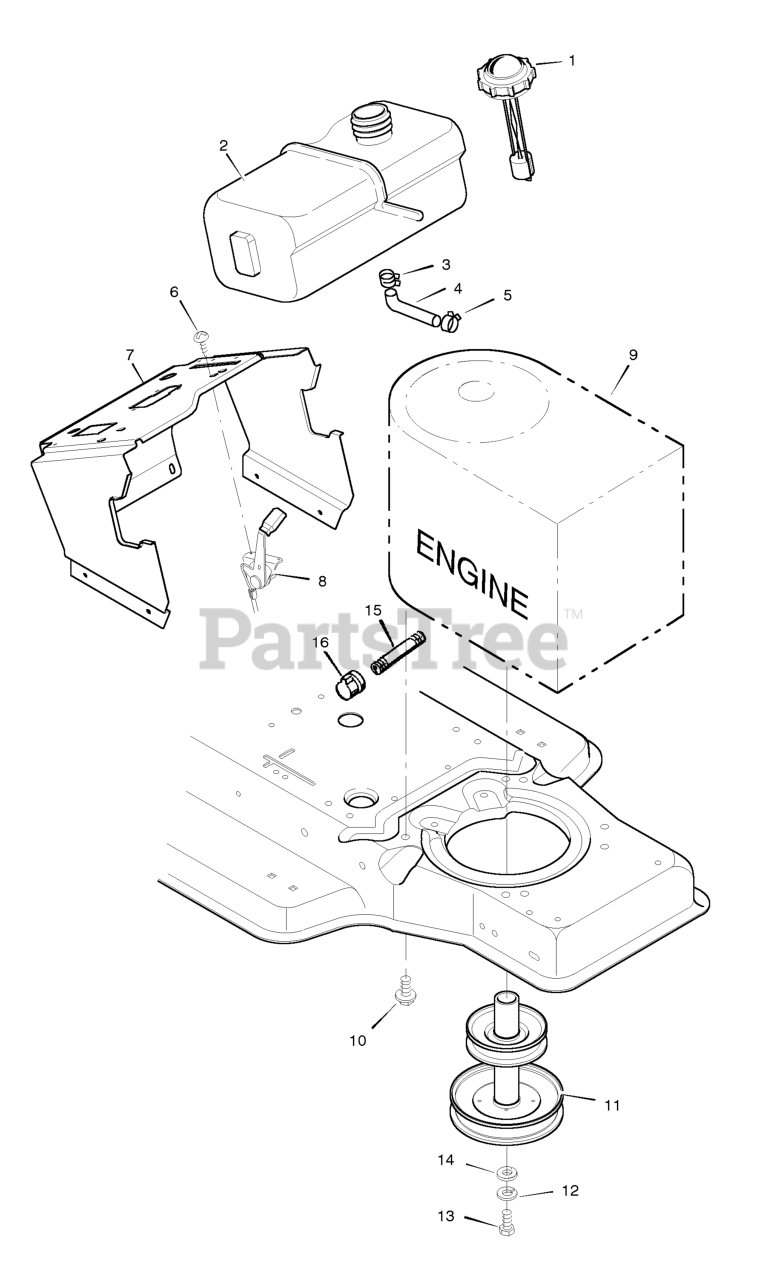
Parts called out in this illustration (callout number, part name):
1	Fuel Cap
2	Fuel Tank
3	Hose Clamp
4	Fuel Line
5	Hose Clamp
7	Support, Dash
8	Throttle Control
9	Engine *
10	Bolt, Engine Mount
11	Stack Pulley Assembly
12	Lockwasher
13	Bolt, Hex
15	Pipe, Oil Drain
16	Cap, Oil Drain
